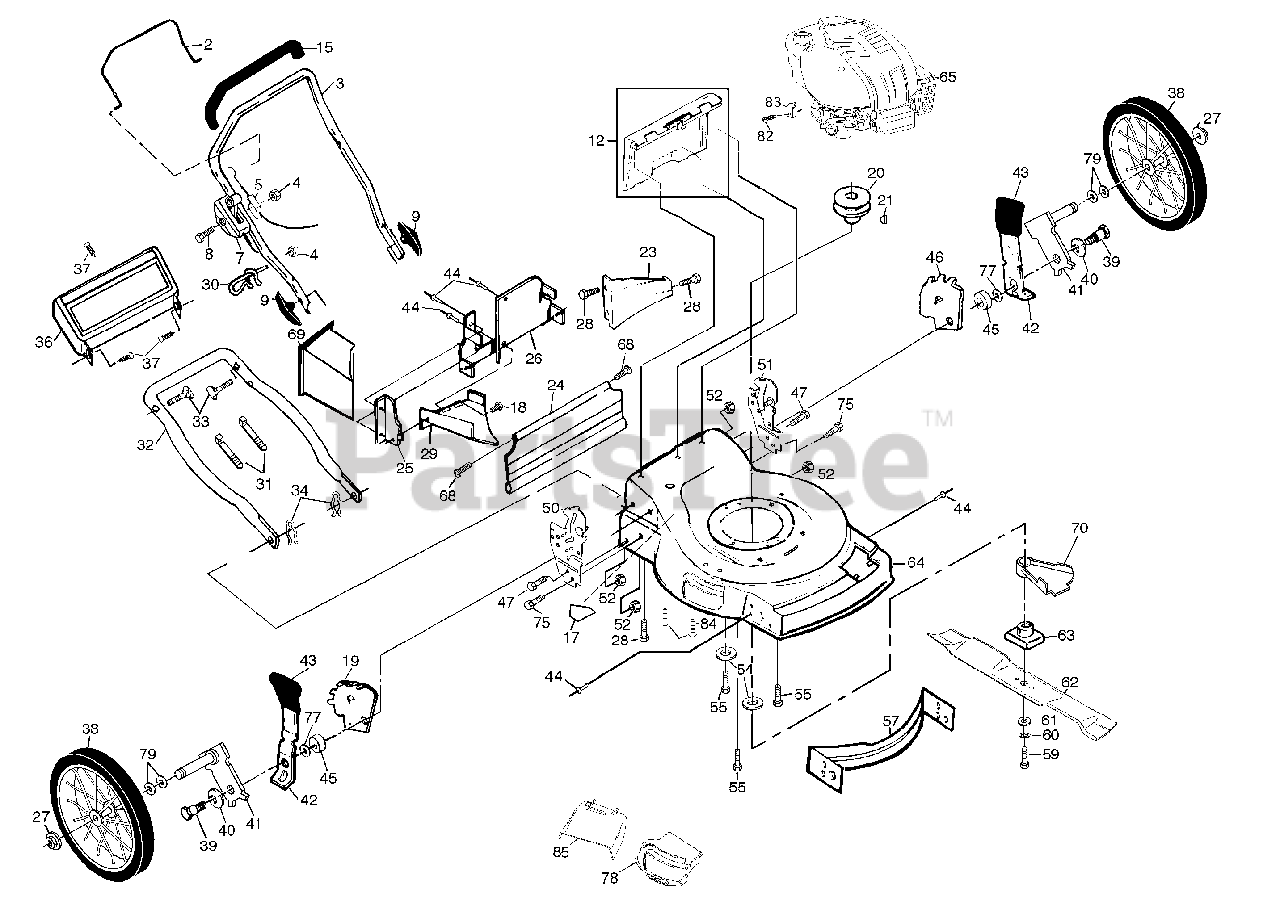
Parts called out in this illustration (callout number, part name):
2	Control Bar
3	Upper Handle
4	Locknut
5	Engine Zone Control Cable
7	Throttle Control
8	Hex Washer Head Screw 1/4-20 x 2-1/8
9	Handle Knob
12	Rear Door Kit
15	Handle Grip
17	Danger Decal
19	Wheel Adjusting Bracket
20	Engine Pulley
21	Hi Pro Key #505
23	Rear Baffle
24	Rear Skirt
25	Side Baffle
26	Back Plate
27	Flanged Locknut
28	Screw Hex Head 1/4-20 x 1/2
29	Discharge Baffle
30	Rope Guide
31	Wire Tie
32	Lower Handle
33	Handle Bolt
34	Hairpin Cotter
36	Trim Plate Assembly
37	Push-in Fastener
38	Wheel & Tire Assembly
39	Shoulder Bolt
40	Spring Washer
41	Axle Arm
42	Selector Spring
43	Selector Knob
45	Spacer
46	Wheel Adjusting Bracket
47	Self-tapping Screw 5/16-18 x 3/4
50	Handle Bracket (Right)
51	Handle Bracket (Left)
52	Locknut 3/8-16
55	Hex Head Thread Rolling Screw 3/8-16 x 1-1/8
57	Front Baffle
59	Hex Head Machine Screw 3/8-24 x 1-3/8 Gr. 8
60	Helical Lock Washer
61	Hardened Washer
63	Blade Adapter
64	Lawn Mower Housing Kit
65	Engine
68	Hinge Screw
69	Mulcher Plug
70	Debris Shield
77	Flat Washer
78	Combi-Cut Door Assm.
79	Wave Washer
83	Engine Clamp
84	Screw
85	Clip on Guard
